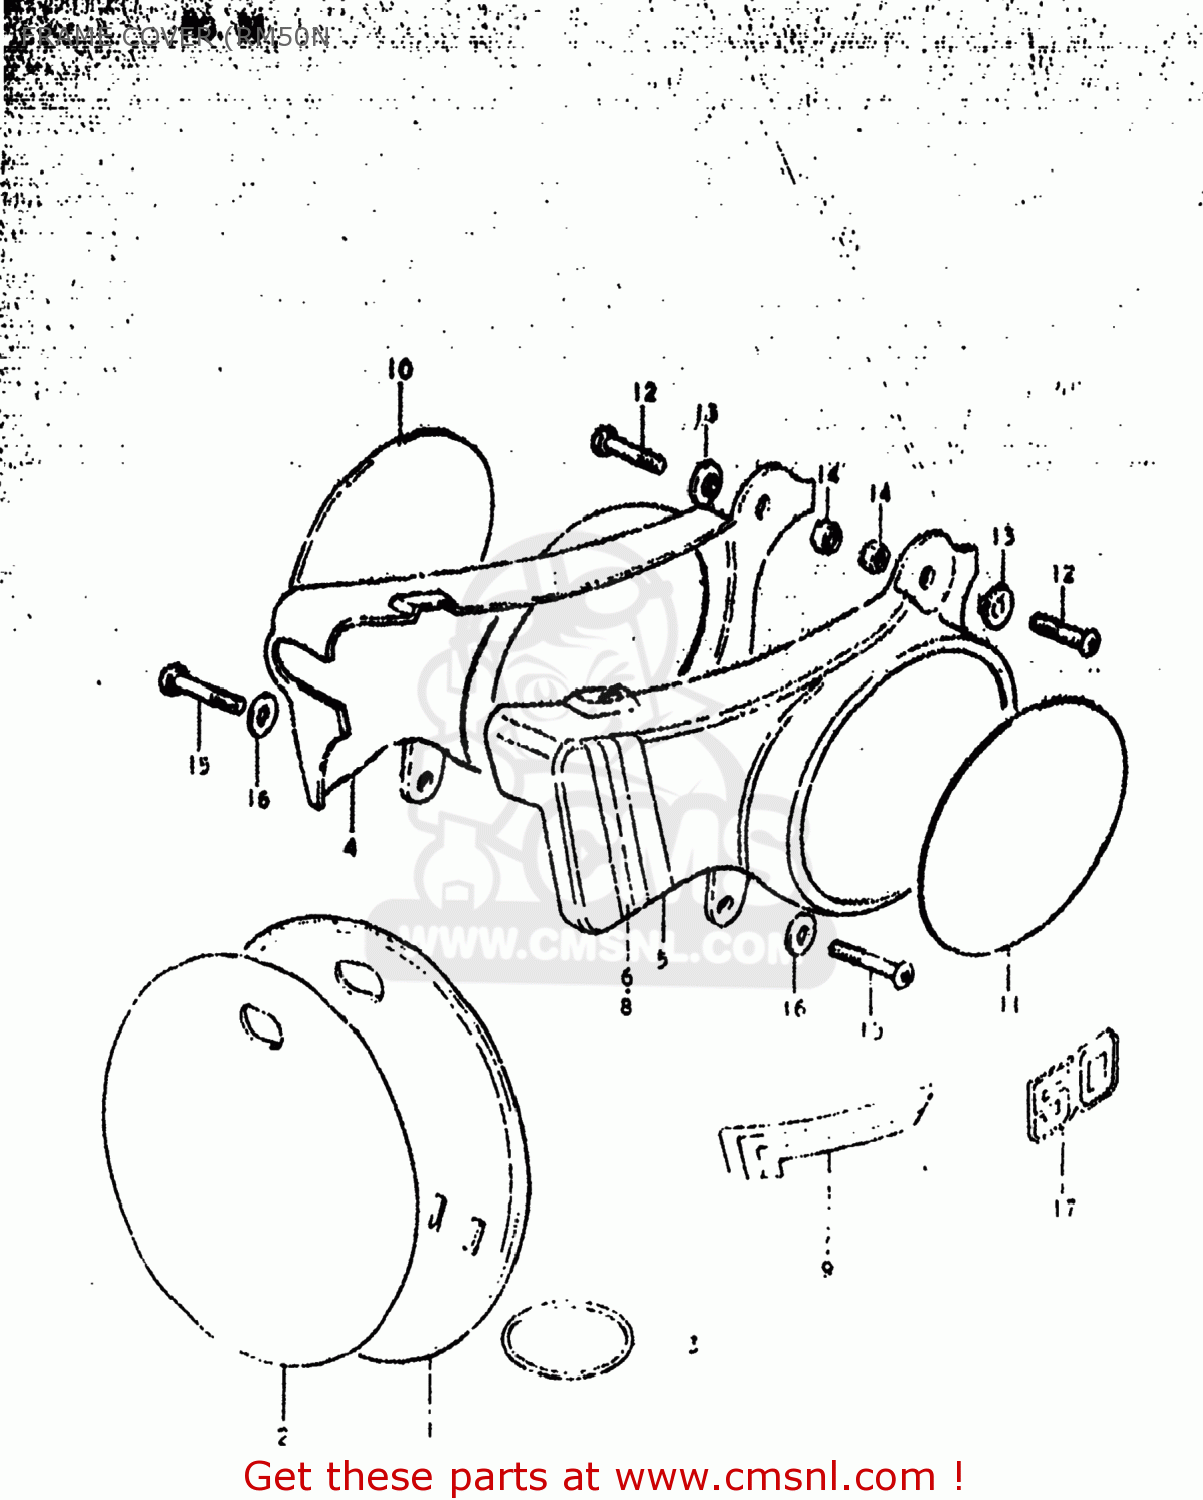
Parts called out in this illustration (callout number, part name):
1	PLATE,NUMBER,FRONT
2	EMBLEM,FRONT NUMBER PLATE
3	O-RING
4	COVER,FRAME,RIGHT
5	COVER,FRAME,LEFT
6	TAPE,FRAME COVER
7	TAPE,FRAME COVER
8	TAPE,FRAME COVER
9	TAPE,FRAME COVER
10	TAPE,FRAME COVER NUMBER PLATE
11	LABEL,FRAME COVER
12	SCREW
13	WASHER
14	NUT
15	SCREW
16	WASHER
17	EMBLEM
